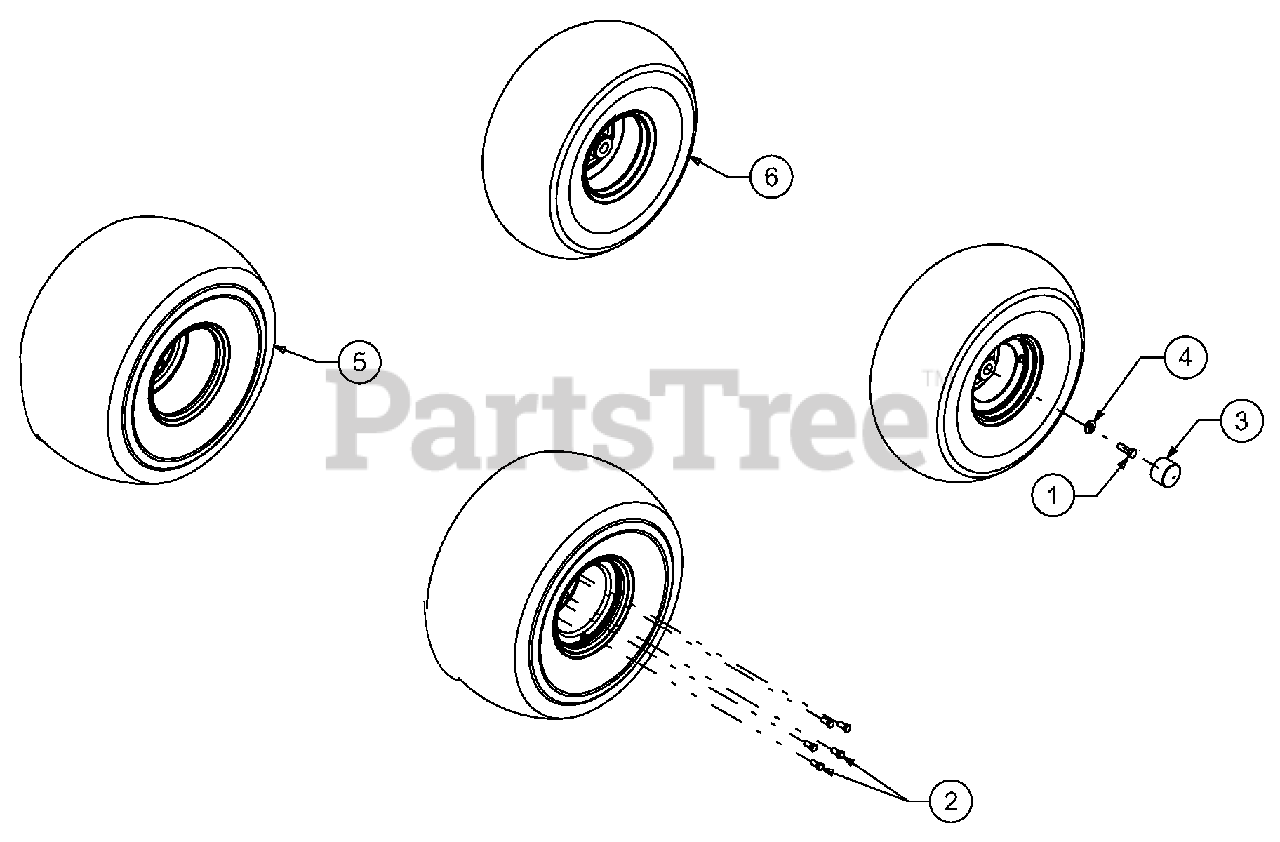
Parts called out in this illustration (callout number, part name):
1	Hex Screw, 1/2-13 x 1.5, Gr5
2	Nut, Hex 7/16-20
3	Washer, Flat, .531 x 1.25 x .181
4	Dust Cover
5	Wheel Assembly, 22 x 11 x 10 RH (AT)
5	Wheel Assembly, 22 x 11 x 10 LH (AT)
6	Wheel Assembly, 25 x 11 x 10 LH (AT)
6	Wheel Assembly, 25 x 11 x 10 RH (AT)
